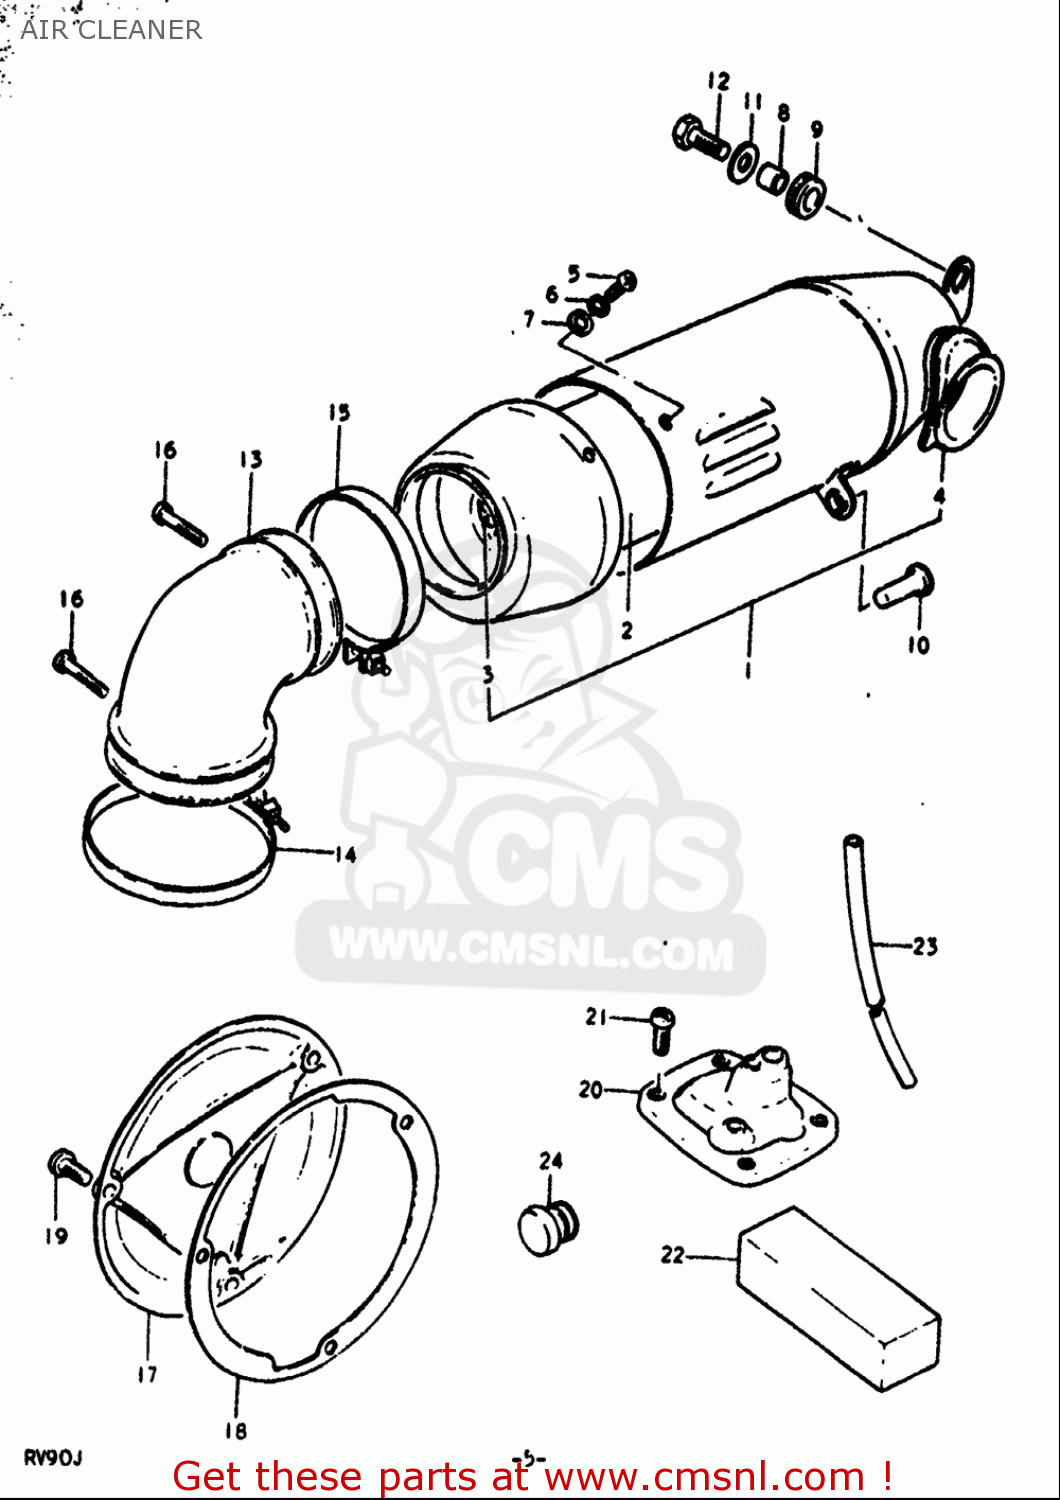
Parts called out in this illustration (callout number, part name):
2	FILTER ASSY
3	FILTER,AIR CLEANER
5	SCREW
6	WASHER,LOCK
7	WASHER
8	SPACER,6.5X9X7
9	CUSHION
11	WASHER(6.5X20X1.2)
12	BOLT
14	CLAMP
15	CLAMP
16	SCREW
17	CAP,CARBURETOR INSPECTION
18	GASKET,CARB INSPECTION CAP (NAS)
19	SCREW
20	COVER,CARBURETOR TOP
21	SCREW
22	SEAL,DUST
24	Plug
